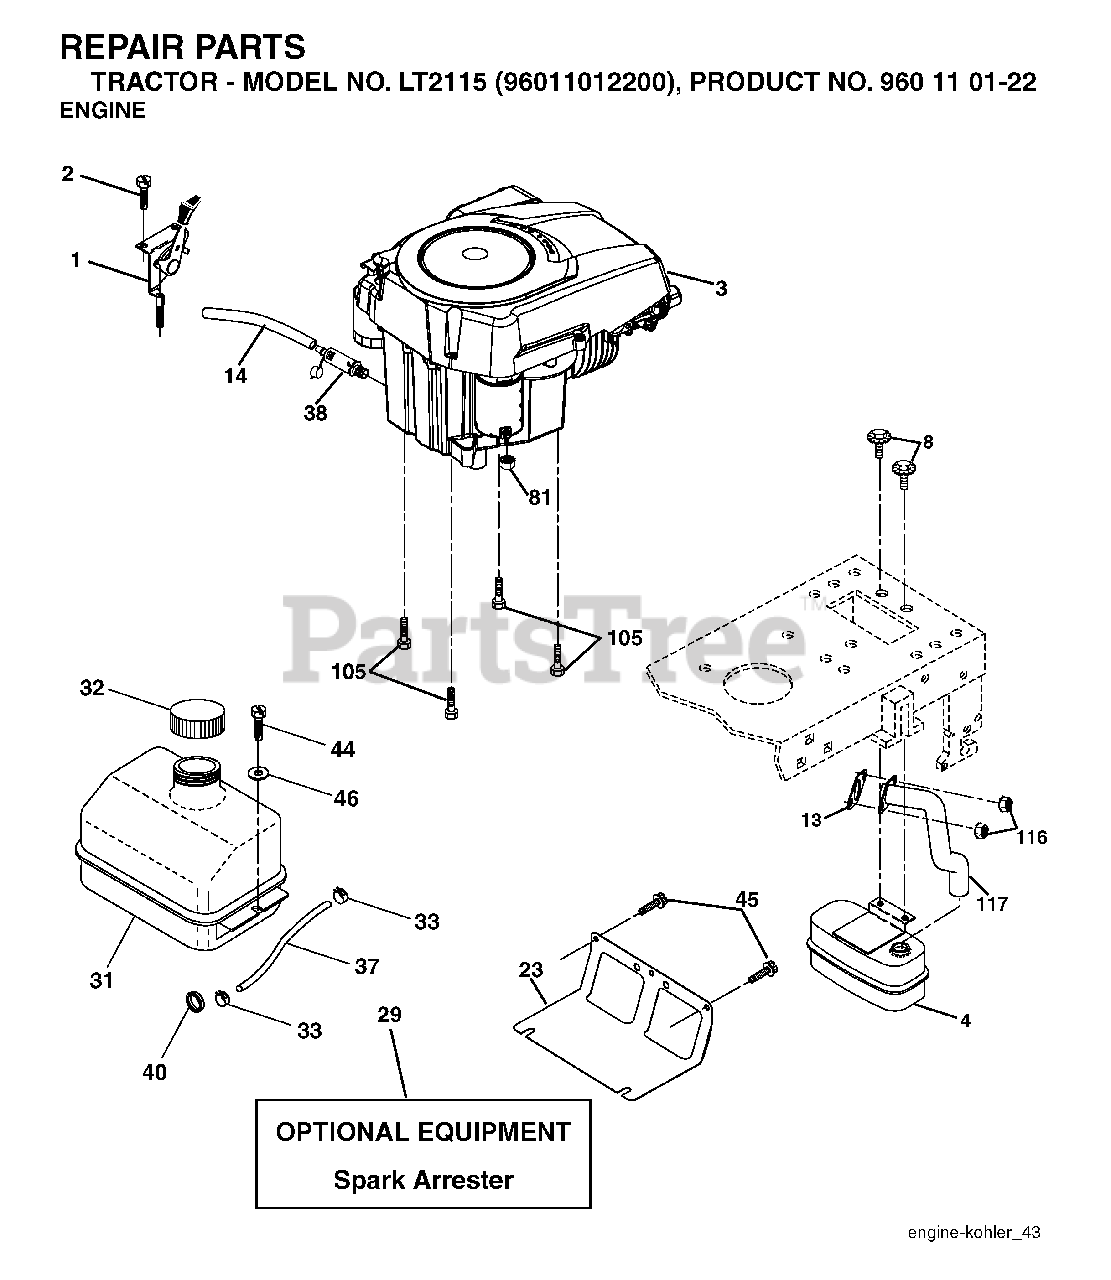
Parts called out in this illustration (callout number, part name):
1	CONTROL.THROTTLE.LT/YT
2	SCREW
4	MUFFLER.SINGLE.CYL.KOHL/B&S
8	BOLT, 5/16-18 X 1 3/4
13	GASKET ENGINE
14	TUBE, DRAIN OIL ASM.
23	SHEILD.BROWNING.DBR.GUARD
29	ARRESTER SPARK (OPTIONAL)
31	TANK FUEL FRONT
32	FUEL CAP
33	HOSE CLAMP
37	LINE.FUEL.20
38	PLUG DRAIN OIL EASY
40	GROMMET T
44	SCREW HEXWSHR 1/4-20X3/4
45	SCREW, 3/8-16X3/4
81	NUT
105	SCREW 3/8-16X1
116	NUT.HEX.FLANGE.TOPLOCK
117	TUBE EXHAUST
